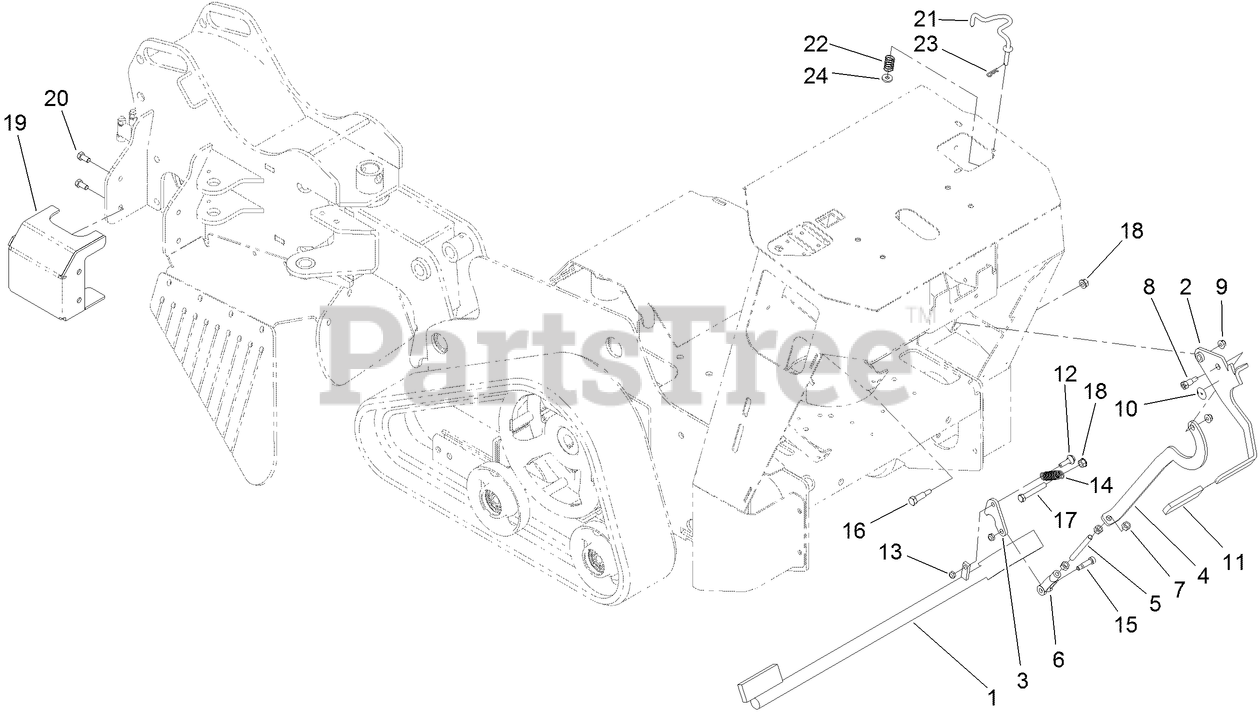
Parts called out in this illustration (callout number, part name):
1	BRAKE BAR ASM
2	BRAKE HANDLE ASM
3	LINK-MOUNTING
4	PLATE-BRAKE
5	ROD-THREADED
6	YOKE-LINKAGE, BRAKE
7	NUT-HEX
8	BOLT-SHOULDER
9	NUT-HF, NI
10	DECAL-PARKING BRAKE
11	GRIP-HANDLE
12	SCREW-SHOULDER
13	NUT-LOCK, NI
14	SPRING-IDLER
15	BOLT-SHOULDER
16	SCREW-SHOULDER, HH
17	SCREW-HH
18	NUT-FLANGE
19	COVER ASM
20	SCREW-HH
21	ROD-INTERLOCK
22	SPRING-CONTROL
23	PIN-COTTER
24	WASHER-FLAT
